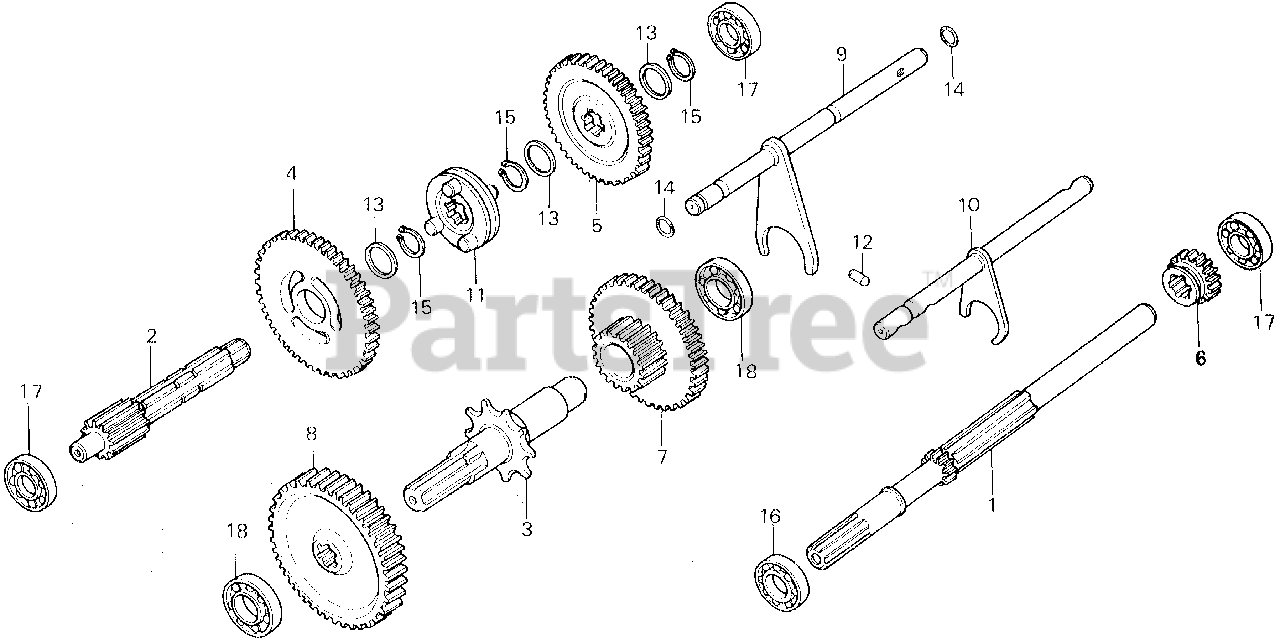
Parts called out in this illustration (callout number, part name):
1	SHAFT, INPUT
2	COUNTERSHAFT
3	SHAFT, FINAL
4	GEAR, COUNTERSHAFT FIRST (NOT AVAILABLE)
5	GEAR, COUNTER
6	GEAR, CHANGE
7	GEAR, REVERSE IDLE
8	GEAR, FINAL
9	SHAFT, MAIN GEARSHIFT FORK
10	SHAFT, SHIFT FORK REVERSE
11	INSULATOR, PLATE (NOT AVAILABLE)
12	PIECE, INTERLOCK
13	WASHER, THRUST (17MM)
14	O-RING (8.8X1.9)
15	CIRCLIP (OUTER) (17MM)
16	BEARING, RADIAL BALL (6003)
17	BEARING, RADIAL BALL (6202)
18	BEARING, RADIAL BALL (6203)
